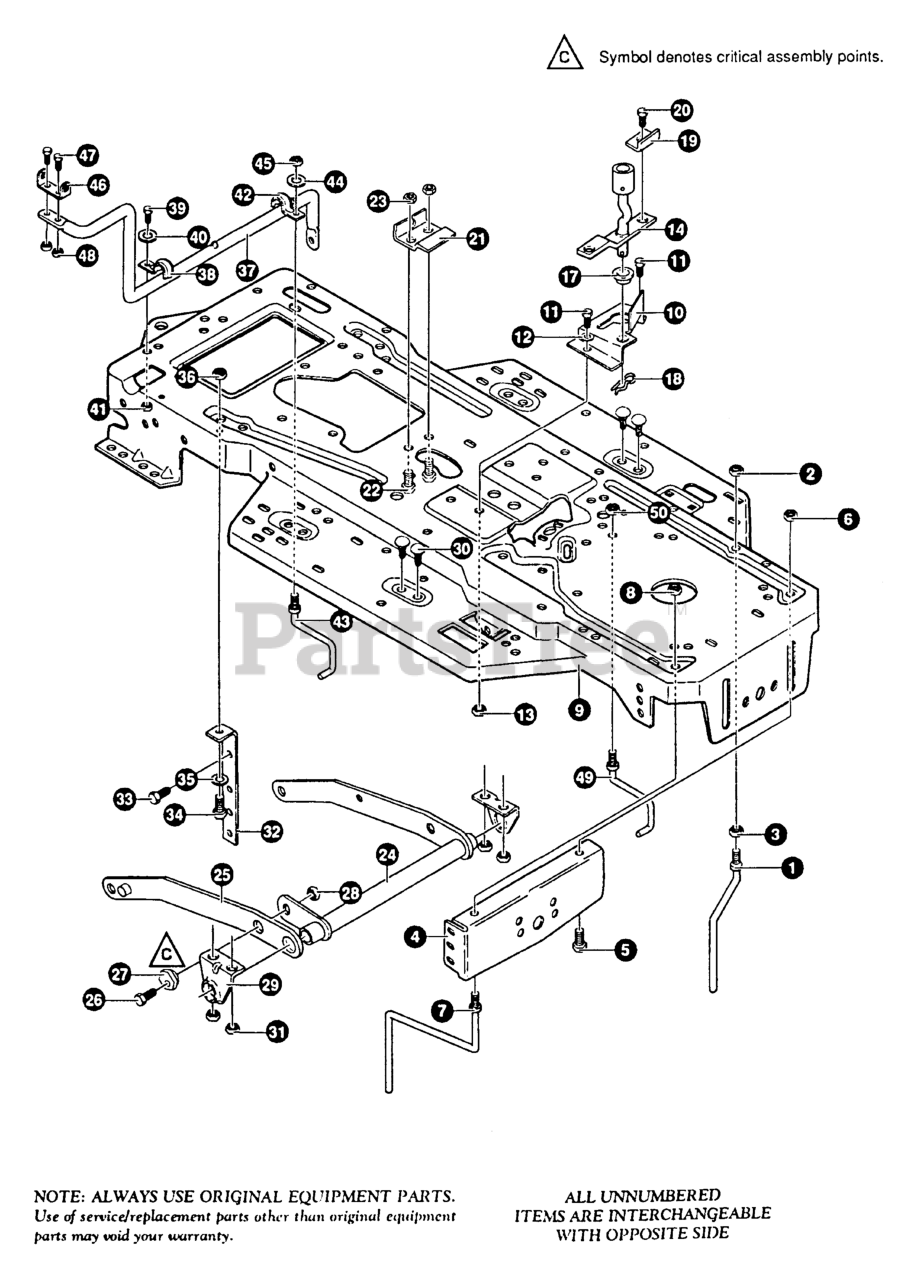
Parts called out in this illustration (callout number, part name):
1	GUIDE, BELT SHORT
2	NUT, 5/16-18
3	NUT, 3/8-16
4	BRACKET, FRONT AXLE
5	SCREW, 5/16-18 x 0.75
6	NUT, 5/16-18
7	GUIDE, BELT, RIDER
8	NUT, 5/16-18
9	FRAME, MAIN
10	BRACKET, CLUTCH ENGAGE LEVER
11	SCREW, 5/16-18 x 1.00
12	WASHER, FLAT .344 X .69 X .065
13	NUT, 5/16-18
14	ASSEMBLY, CLUTCH LEVER LOWER
17	BEARING
18	PIN, HAIR
19	BRACKET, SWITCH ENGAGE
20	SCREW, 5/16-18 x 0.75
21	BRACKET, FRAME CABLE
22	SCREW, 1/4-20 x .75
23	NUT, 1/4-20
24	LIFT ASSEMBLY, LH
25	LIFT ASSEMBLY, RH
26	SCREW, 5/16-18 x 1.00
27	NUT, ADJUST
28	NUT, 5/16-18
29	BRACKET, REAR HANG SUSP
30	BOLT, 5/16-18 X .63
31	NUT, 5/16-18
32	BRACKET, STABILIZER
33	SCREW, 3/8-16 X 1.25
34	SCREW, 5/16-18 x 1.00
35	WASHER, FLAT .344 X .69 X .065
36	NUT, 5/16-18
37	LEVER, SHIFT-LOWER
38	CLIP-SHIFT LEVER
39	SCREW, 5/16-18 x 0.75
40	WASHER, FLAT .391 X 1.00 X .125
41	NUT, 5/16-18
42	CLIP- SHIFT LEVER
43	GUIDE, BELT
44	WASHER, FLAT .391 X 1.00 X. 125
45	NUT, 5/16-18
46	BRACKET, PIVOT SHIFT LEVER
47	SCREW, 1/4-20 X .75
48	NUT, 1/4-20
49	GUIDE, BELT, RH
50	NUT, 5/16-18
